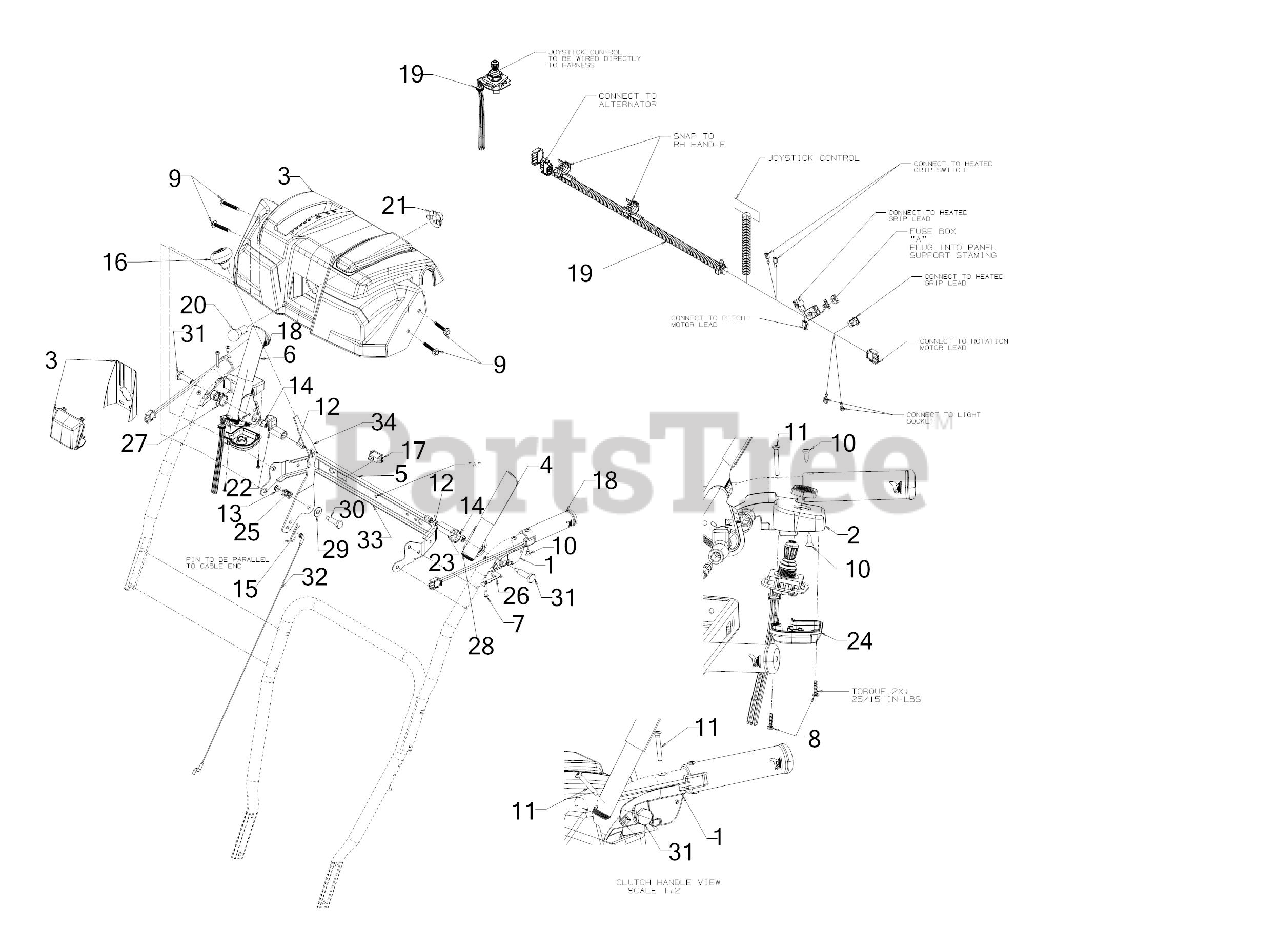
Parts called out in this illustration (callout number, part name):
1	CLUTCH LOCK HANDLE ASSEMBLY (LH)
2	CLUTCH LOCK HANDLE ASSEMBLY (RH)
3	4-WAY HANDLE PANEL ASSEMBLY
4	HANDLE ASSEMBLY (LH)
6	ENGAGEMENT HANDLE ASSEMBLY (RH) (RED)
7	SCREW #8-16 x .50
8	SCREW .159 x .610
9	SCREW 1/4-20 x 1.625
10	SCREW #10-16 x .625
11	SCREW #10-24 x 1.375
12	SCREW 1/4-20 x .50
13	FLANGE LOCK NUT
14	HEX NUT W/PATCH
15	INTERNAL COTTER PIN
16	SHIFT KNOB
17	HEATED GRIP SWITCH
19	4-WAY ELEC/HEAT GRIP HARNESS
21	HEADLIGHT SOCKET
23	CLUTCH LOCK CAM
24	JOYSTICK HOUSING COVER
25	COMPRESSION SPRING
26	CLUTCH SPRING
27	TORSION SPRING
28	RUBBER BUMPER
29	FLAT WASHER
30	SHOULDER SCREW
31	SHOULDER SCREW .437 x 1.345 1/4-20
32	SPEED SELECTOR CABLE (PLASTIC)
33	HANDLE SUPPORT BRACKET
